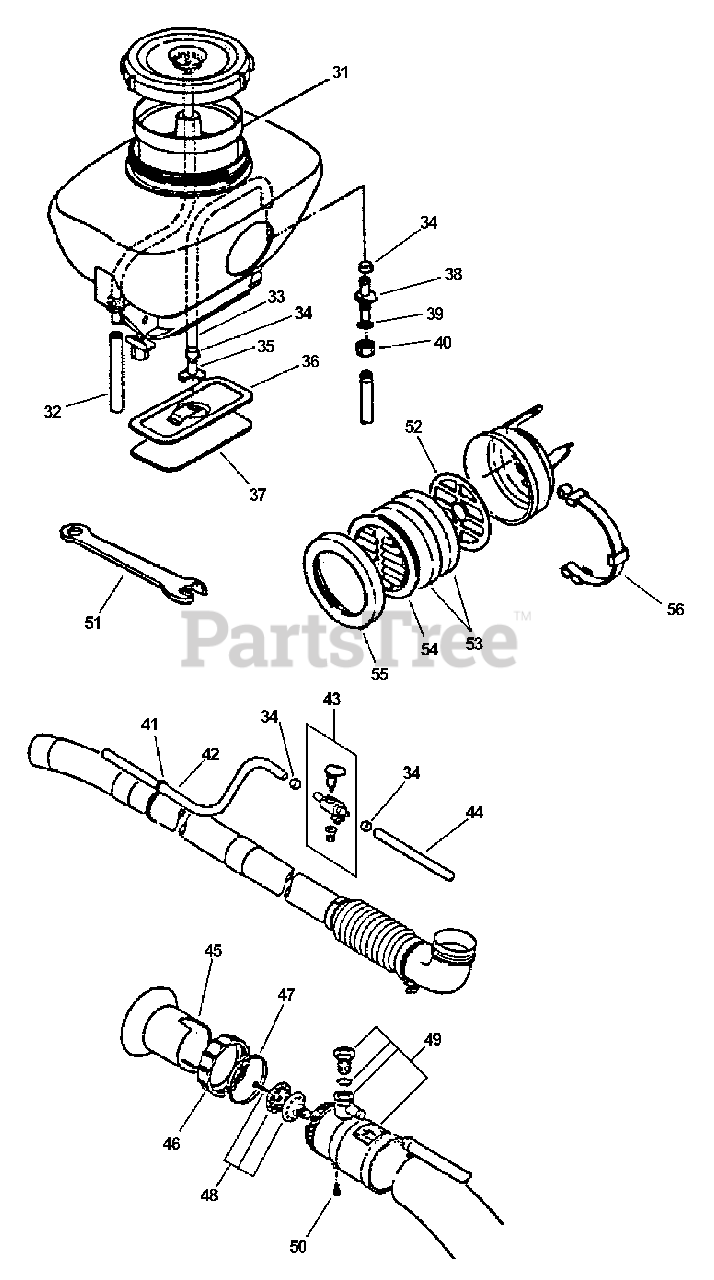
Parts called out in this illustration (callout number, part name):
33	HOSE, FLUID
34	CLIP - 14
35	MOUTH, SUCTION
38	CONNECTOR, PIPE
39	O-RING 3×13
41	CLIP
42	HOSE
43	VALVE ASSY
44	HOSE, FLUID
45	COLLAR, NOZZLE
47	RING, NOZZLE
48	NOZZLE ASSY
49	ADJUSTER, VOLUME
50	SCREW 5×12
51	SPANNER 10×21
52	RETAINER, AIR FILTER
53	FILTER, AIR
54	COVER, AIR FILTER
55	COVER, AIR FILTER
56	CLAMP
